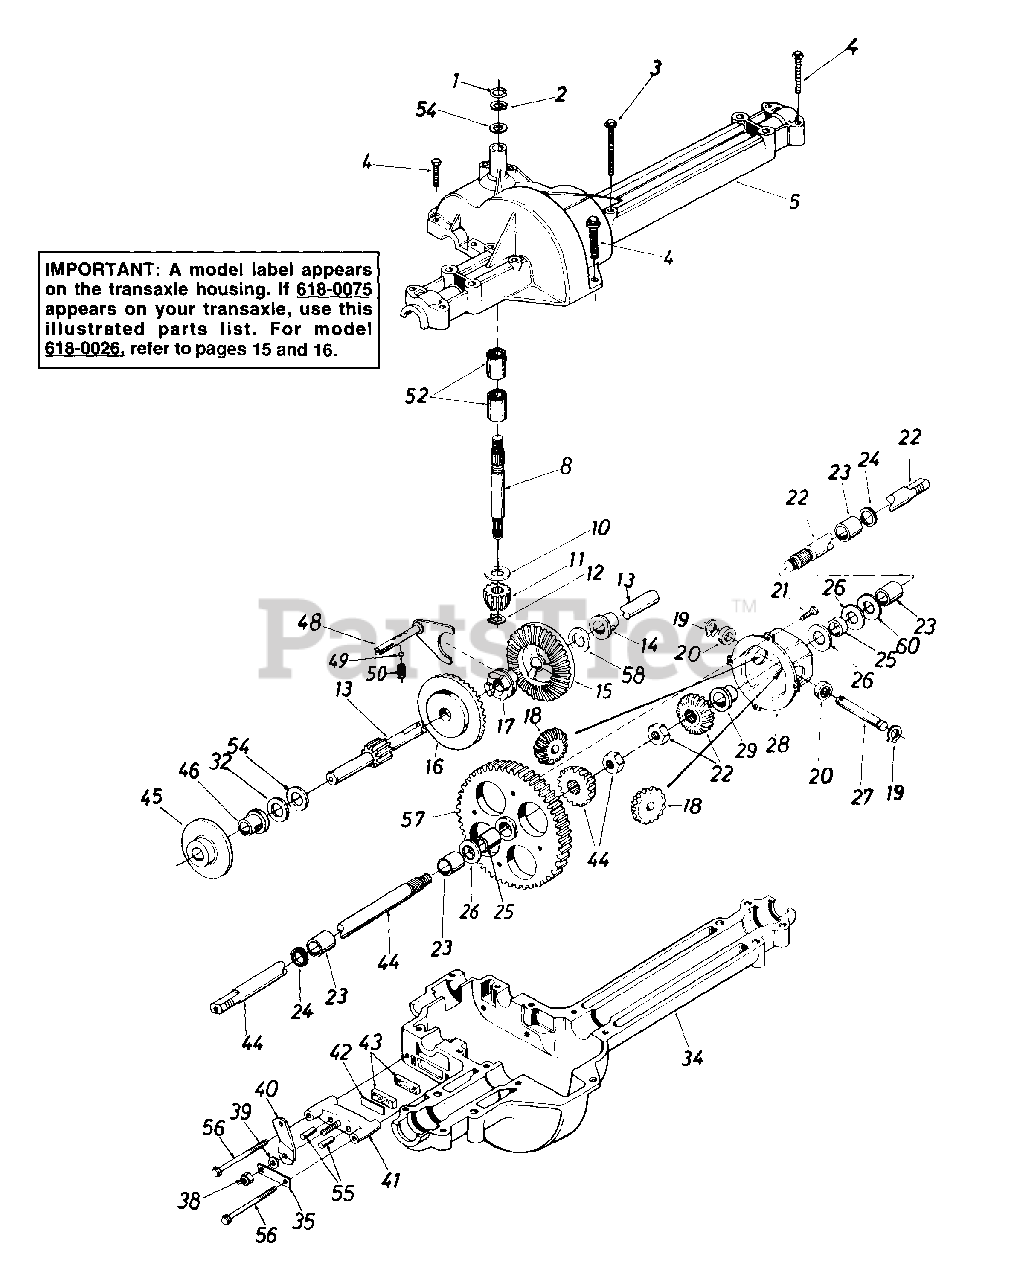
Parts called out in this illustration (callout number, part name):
1	Wire Ring
2	Retaining - Ring
3	Hex Bolt 1/4-20 x 1.75" Lg.
4	Hex Tap Scr. 1/4-20 x 1.25" Lg.
5	Upper Housing
8	Input Shaft
10	Thrust Washer 5/8" I.D. x 1.25" O.D.
11	Pinion Input 14T
12	Retaining Ring
13	Drive Shaft - L.H. Brake
14	Flange Brg. 5/8" I.D. x 3/4" Lg.
15	Bevel Gear 42T - Small I.D.
16	Bevel Gear 42T - Large I.D.
17	Clutch Collar
18	Miter Gear 15T (H.D.)
19	Snap Ring
20	Thrust Bearing
21	Pan Head Scr. 1/4-20 x .50" Lg. w/Patch
22	Axle R.H. Ass'y.
23	Sleeve Bearing 3/4" I.D. x 1.0" Lg.
24	Oil Seal 3/4" I.D.
25	Axle Spacer
26	Fl-Wash. .760" I.D. x 1.5" O.D.
27	Cross Shaft
28	Differential Can Ass'y.
32	Thrust Wash. 5/8" I.D. x 1" O.D. x .025" Thk.
34	Lower Housing
35	Anti-Rotation Brkt.
38	Hex Nut 5/16-24 Thd.
39	Fl-Wash. .344" I.D. x .875" O.D.
40	Actuating Arm
41	Brake Yoke
42	Puck Plate
43	Brake Puck
44	Axle L.H. Ass'y.
45	Brake Disc
46	Flange Bearing 5/8" I.D. x 15/16" Lg.
48	Shift Fork Ass'y.
49	Ball Detent .250" Dia.
50	Spring Detent
52	Needle Brg. 5/8" I.D. x 1/2" Lg.
54	Fl-Wash. 5/8" I.D. x 1" O.D. x .020 Thk.
55	Actuating Pin 5/16" Dia.
56	Hex Wash Hd. Self-Tap Scr. 1/4-20 Thd.
57	Differential Gear 58T
58	Fl-Wash. 5/8" I.D. x 1" O.D. x .020 Thk.
60	Fl-Wash. .76" I.D. x 1.5" O.D. x .010" Thk.
